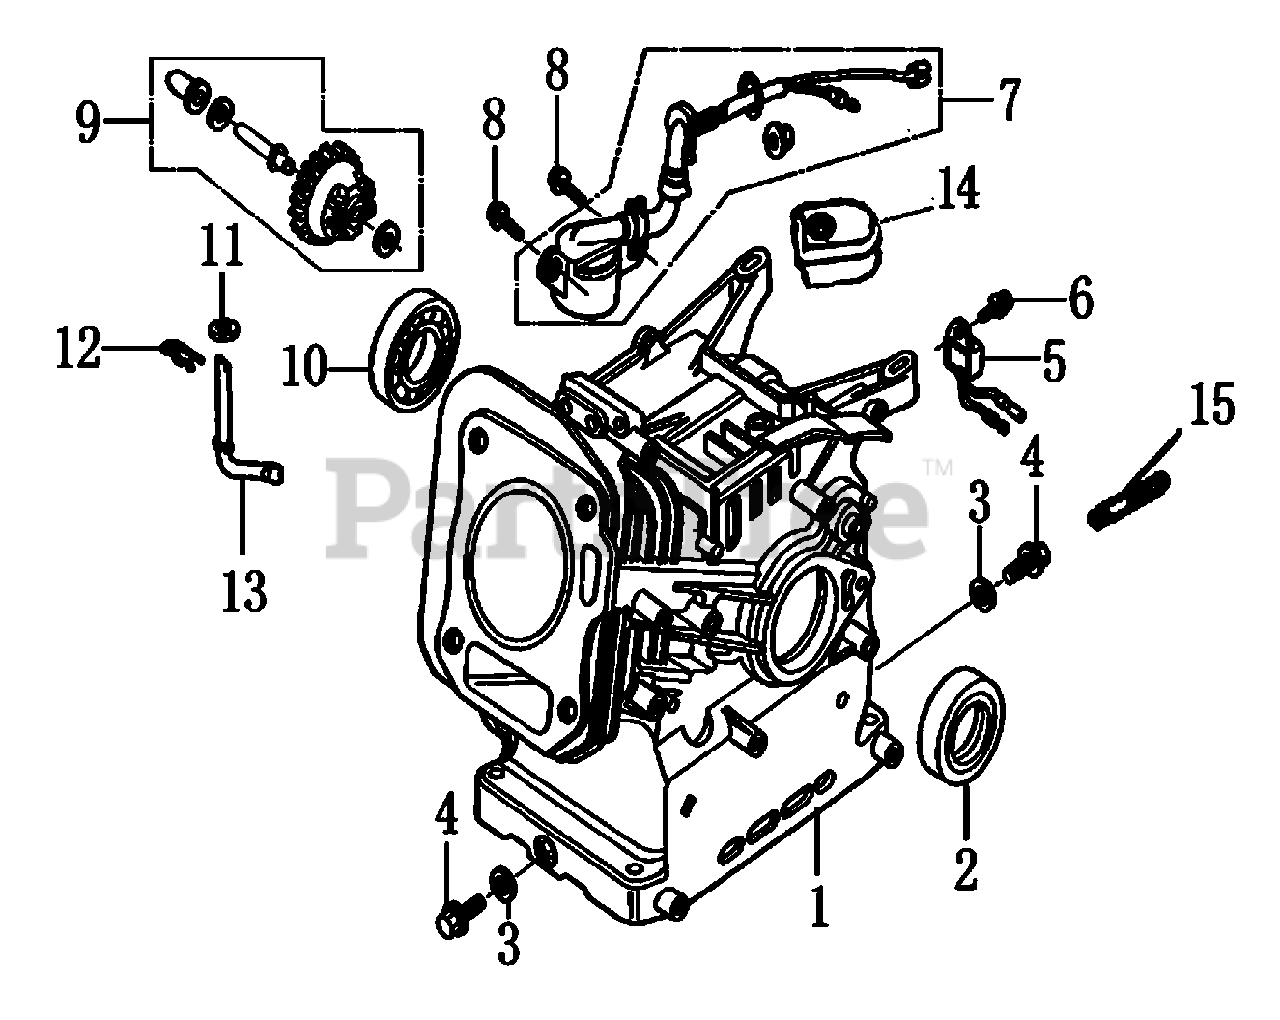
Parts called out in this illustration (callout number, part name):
1	CRANKCASE
2	OIL SEAL 25X41.25X6
3	WASHER, DRAIN PLUG
4	BOLT, DRAIN PLUG
5	ALERT UNIT, LOW OIL
6	BOLT, FLANGE , 6X10
7	OIL LEVEL SWITCH
8	BOLT, FLANGE , 6*14
9	GOVERNOR GEAR ASSY.
10	BEARING, RADIAL BALL
11	WASHER, PLAIN
12	PIN, LOCK
13	SHAFT, GOVERNOR ARM
14	COVER, WIRE
15	CABLE CLEAT
